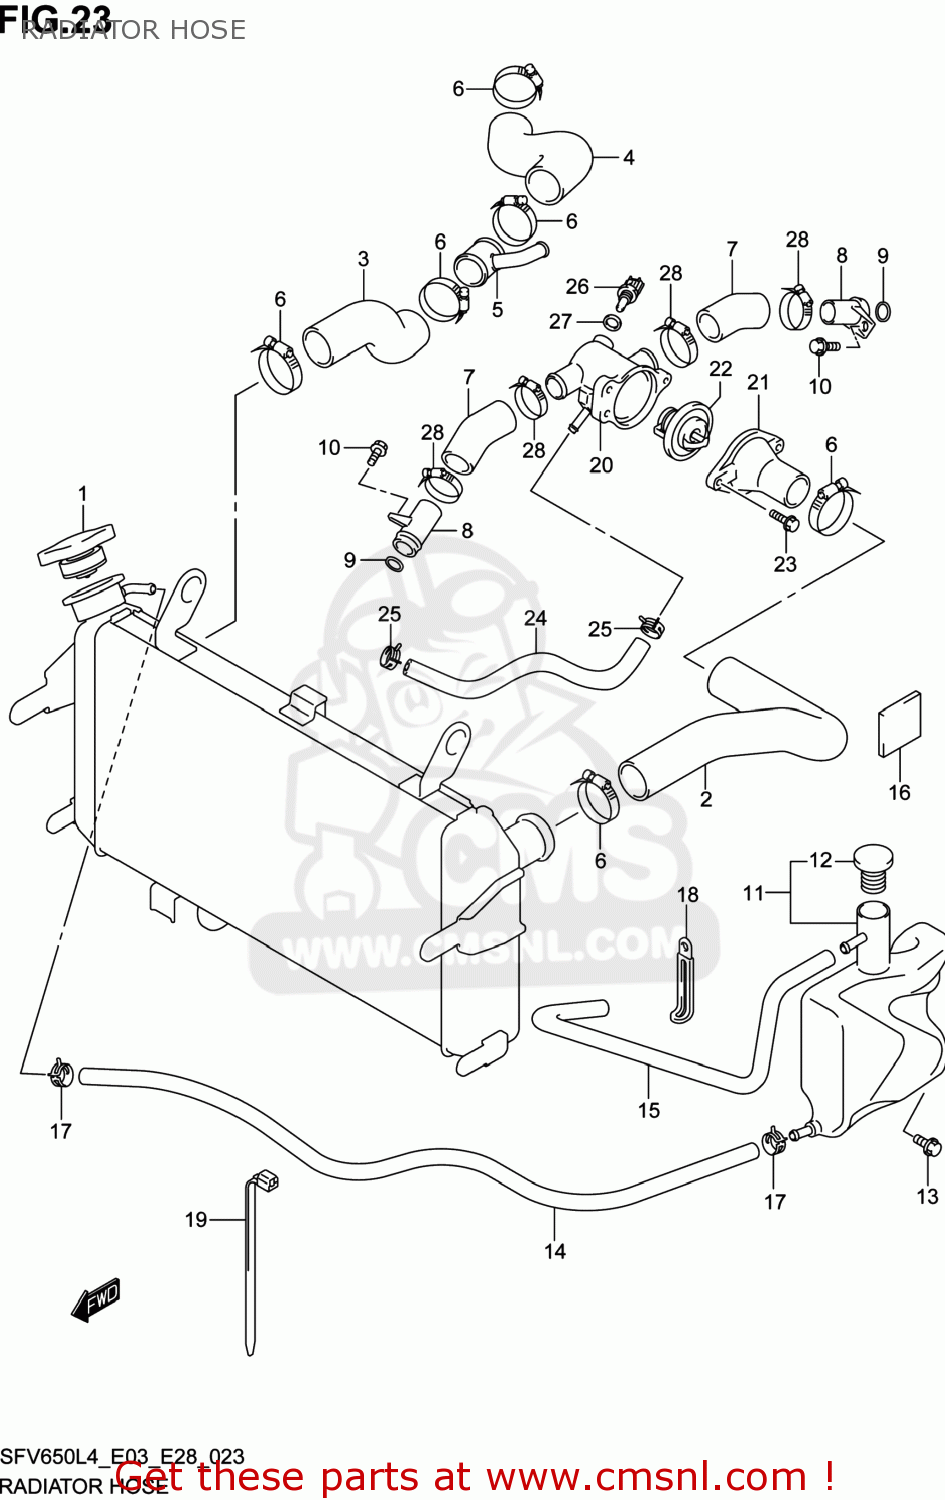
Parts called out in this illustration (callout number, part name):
1	CAP,RADIATOR
2	HOSE,RADIATOR INLET
3	HOSE,RADIATOR OUTLET NO.1
4	HOSE,RADIATOR OUTLET NO.2
5	UNION,WATER HOSE THREE WAY
6	CLAMP
7	HOSE,CONNECTOR INLET
8	UNION,CONNECTOR HOSE
9	O RING(D:3.2,ID:17.8)
10	BOLT
11	TANK ASSY,RESERVOIR
12	CAP,RESERVOIR TANK
13	BOLT(6X12)
14	HOSE,RESERVOIR TANK INLET
15	HOSE,RESERVOIR TANK OVFL
16	CUSHION
17	CLIP
18	CLAMP(L:45)
19	CLAMP(L:190)
20	CONNECTOR,THERMOSTAT INLET
21	CAP,THERMOSTAT CONNECTOR
22	THERMOSTAT,WATER
23	BOLT
24	HOSE,CONNECTOR TO WATER PUMP
25	CLAMP
26	SENSOR,TEMP
27	GASKET(12X17X1) (NAS)
28	CLAMP
